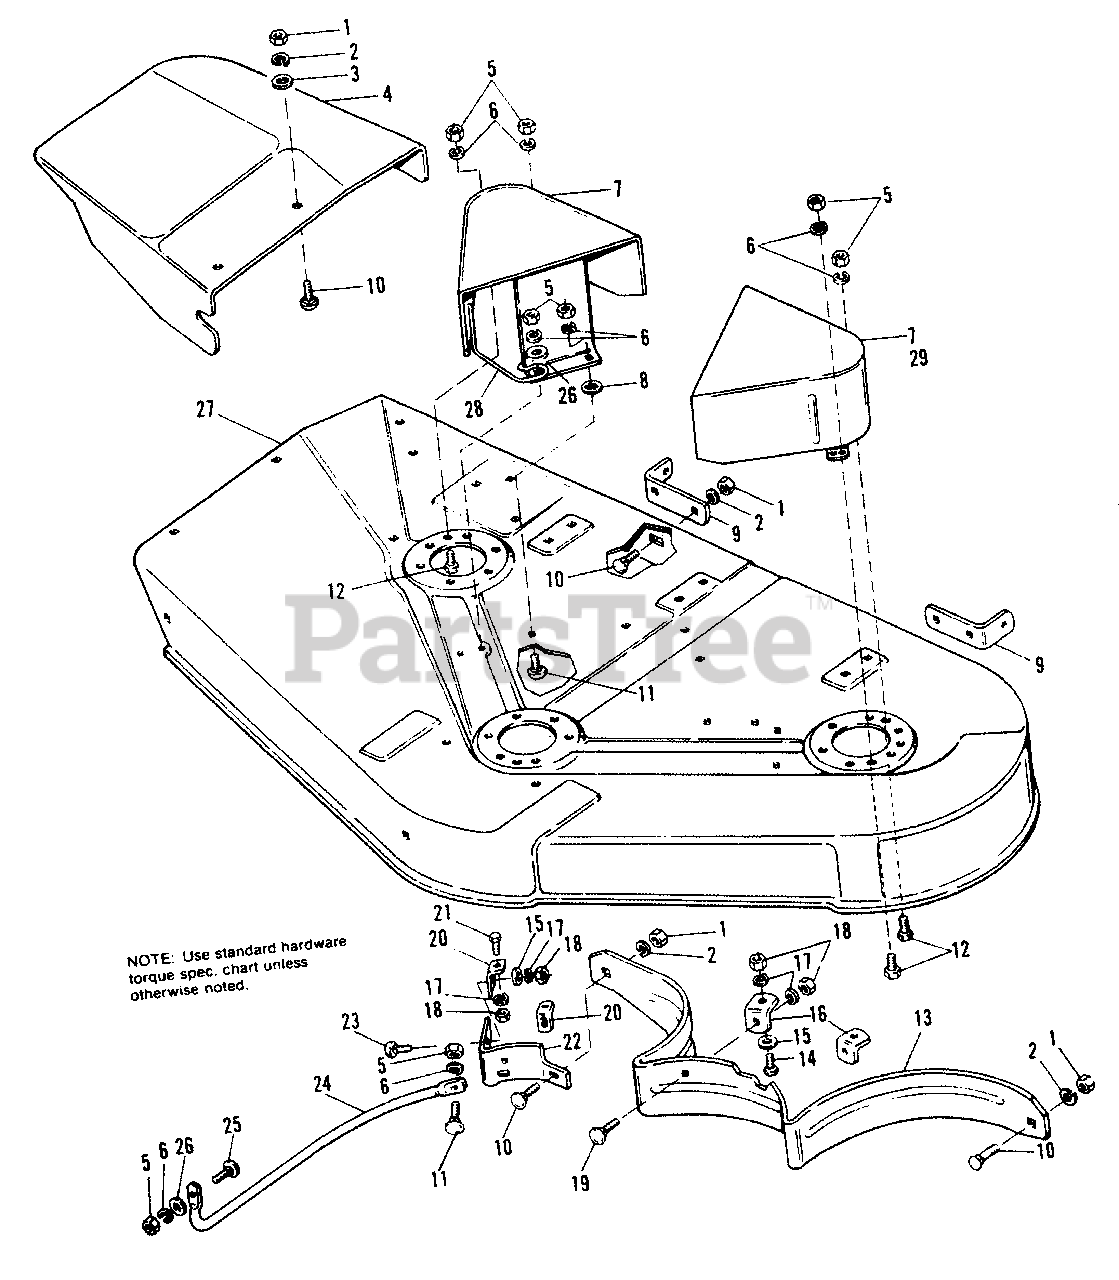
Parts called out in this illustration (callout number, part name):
1	NUT, Hex, 3/8-16
2	LOCKWASHER, 3/8
3	WASHER, Plain, 3/8
5	NUT, Hex, 5/16-18 (Qty. 8 on 42" Mower)
6	LOCKWASHER, 5/16 (Qty. 8 on 42" Mower)
7	ARBOR COVER ASSY. (Qty. 1 on 42" Mower)
8	PUSHNUT, 5/16 (Qty. 2 on 42" Mower)
9	BRACKET, Roller Support
10	BOLT, Carriage, 3/8-16 x 3/4
11	BOLT, Carriage, 5/16-18 x 3/4 (Qty. 2 on 42" Mower)
12	CAPSCREW, Hex, 5/16-18 x 1
13	BAFFLE (48" Mower)
13	BAFFLE (42" Mower)
14	CAPSCREW, Hex, 1/4-20 x 3/4
15	WASHER, 1/4
16	CLIP, Baffle
17	LOCKWASHER, 1/4
18	NUT, Hex, 1/4-20
19	BOLT, Carriage, 1/4-20 x 5/8
20	CLIP GUARD & BAFFLE
21	CAPSCREW, Hex, 1/4-20 x 3/4
22	BAFFLE, Discharge
23	BOLT, Carriage, 1/4-20 x 3/4
24	GUARD, Mower Discharge
25	BOLT, Carriage, 5/16-18 x 1
26	WASHER, 11/32 x 1
27	48" ROTARY MOWER HOUSING KIT
27	42" ROTARY MOWER HOUSING KIT
29	ARBOR COVER ASSY. (42" Mower)
